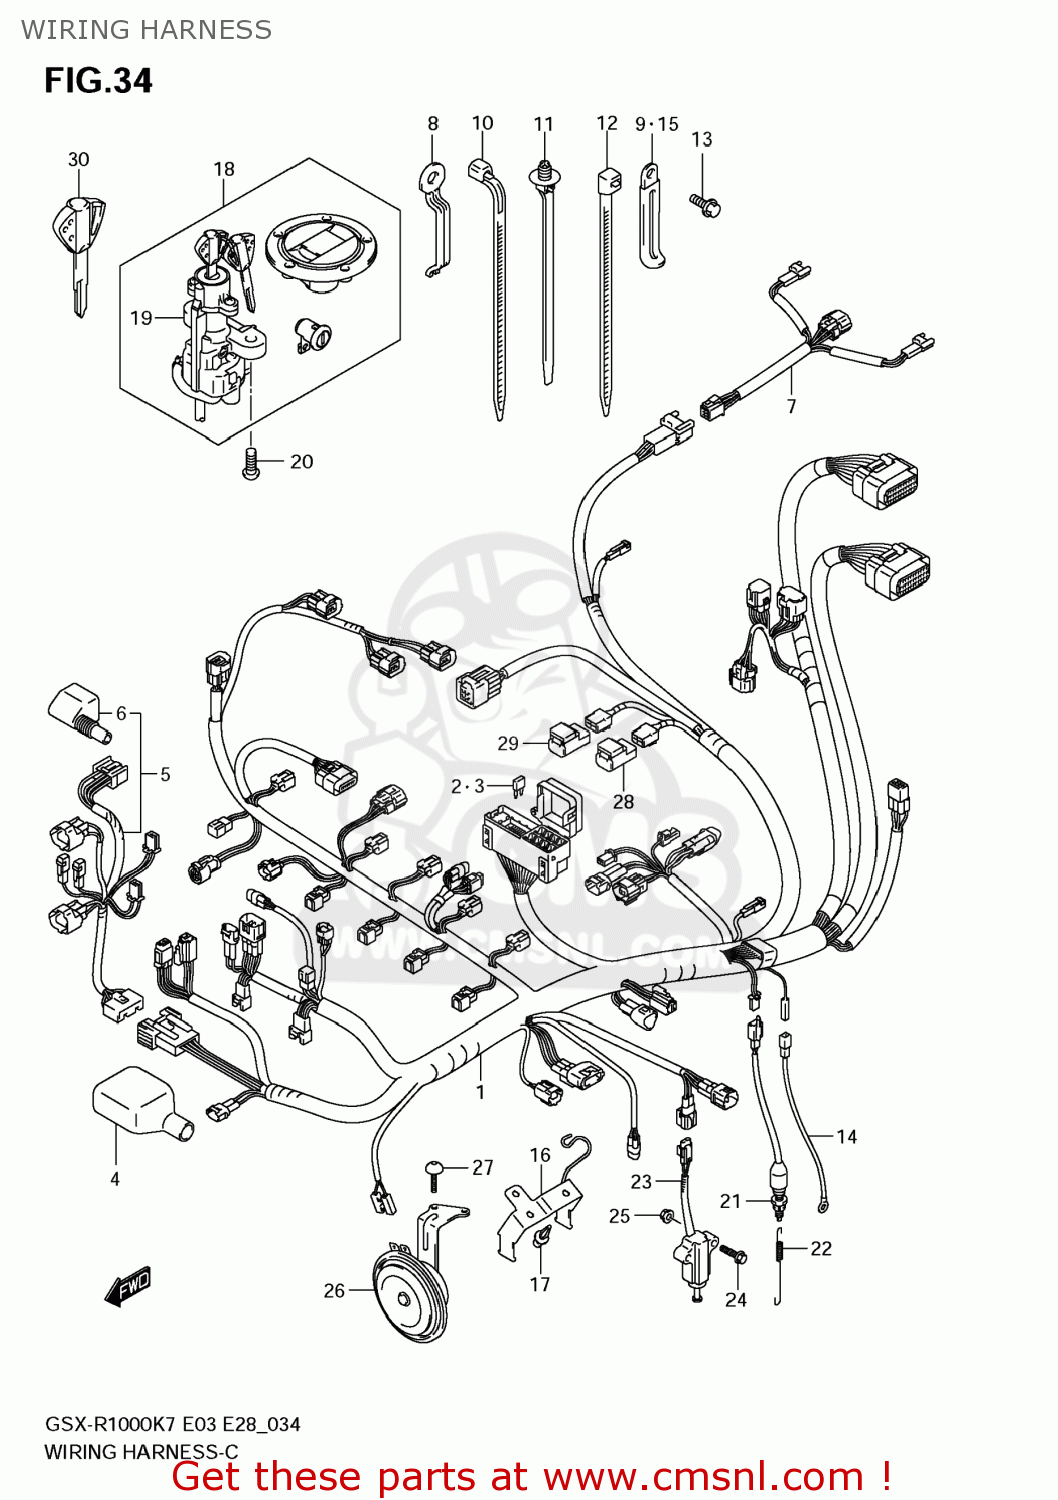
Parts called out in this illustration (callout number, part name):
1	HARNESS,WIRING NO.1
2	FUSE(10A)
3	FUSE(15A)
4	COVER,CONNECTOR
5	HARNESS,WIRING NO.2
6	COVER,SPEEDOMETER COUPLER
7	WIRE,RR COMB
8	CLAMP
9	CLAMP(L:45)
10	CLAMP(L:125)
11	CLAMP(L:154)
12	CLAMP(L:145)
13	BOLT
14	WIRE,OIL PRESSURE SWITCH LEAD
15	CLAMP(L:45)
16	BRACKET,FUSE
17	BOLT
18	LOCK SET
19	LOCK ASSY,STEE
20	BOLT(8X20)
21	SWITCH ASSY,STOP LAMP
22	SPRING
23	SWITCH ASSY,SIDE STAND
24	BOLT(8X35)
25	NUT
26	HORN ASSY
27	BOLT(6X20)
28	RELAY ASSY
29	RELAY ASSY
30	KEY,BLANK(IMMOBII)
